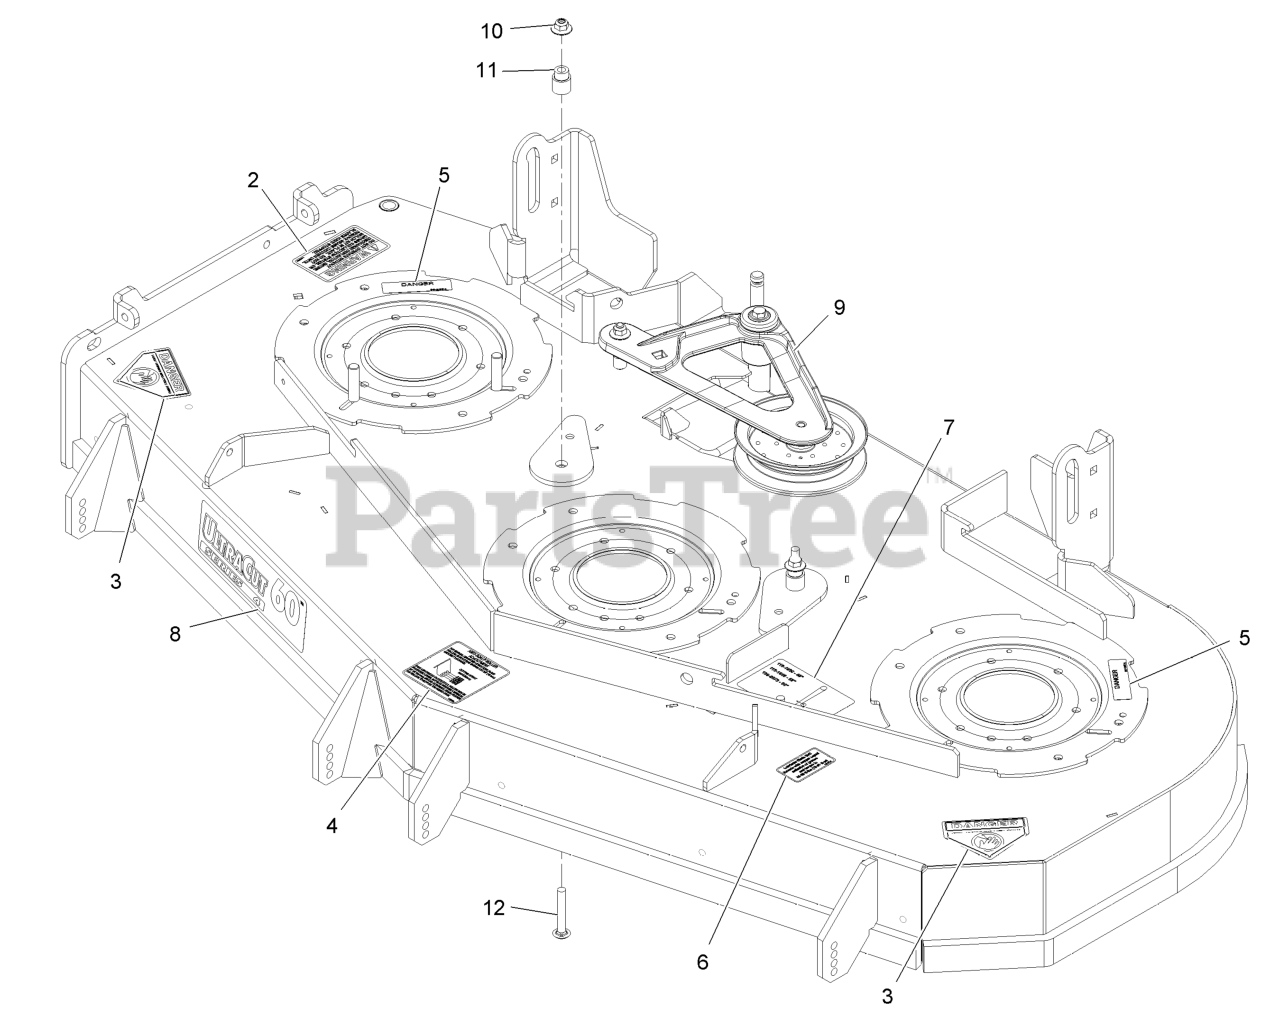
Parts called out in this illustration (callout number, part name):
2	DECAL-WARNING, DISCHARGE
3	DECAL-DANGER
4	DECAL,ANTISCALP
5	DECAL-COVER, MISSING
6	DECAL,BOLT TORQUE
7	DECAL-BELT ROUTING
8	DECAL,ULTRACUT 60 SERIES
9	DECK IDLER ASM
10	Nut-Nyloc 3/8-16 Flg
11	BUSHING-IDLER
12	SCREW-CARR
